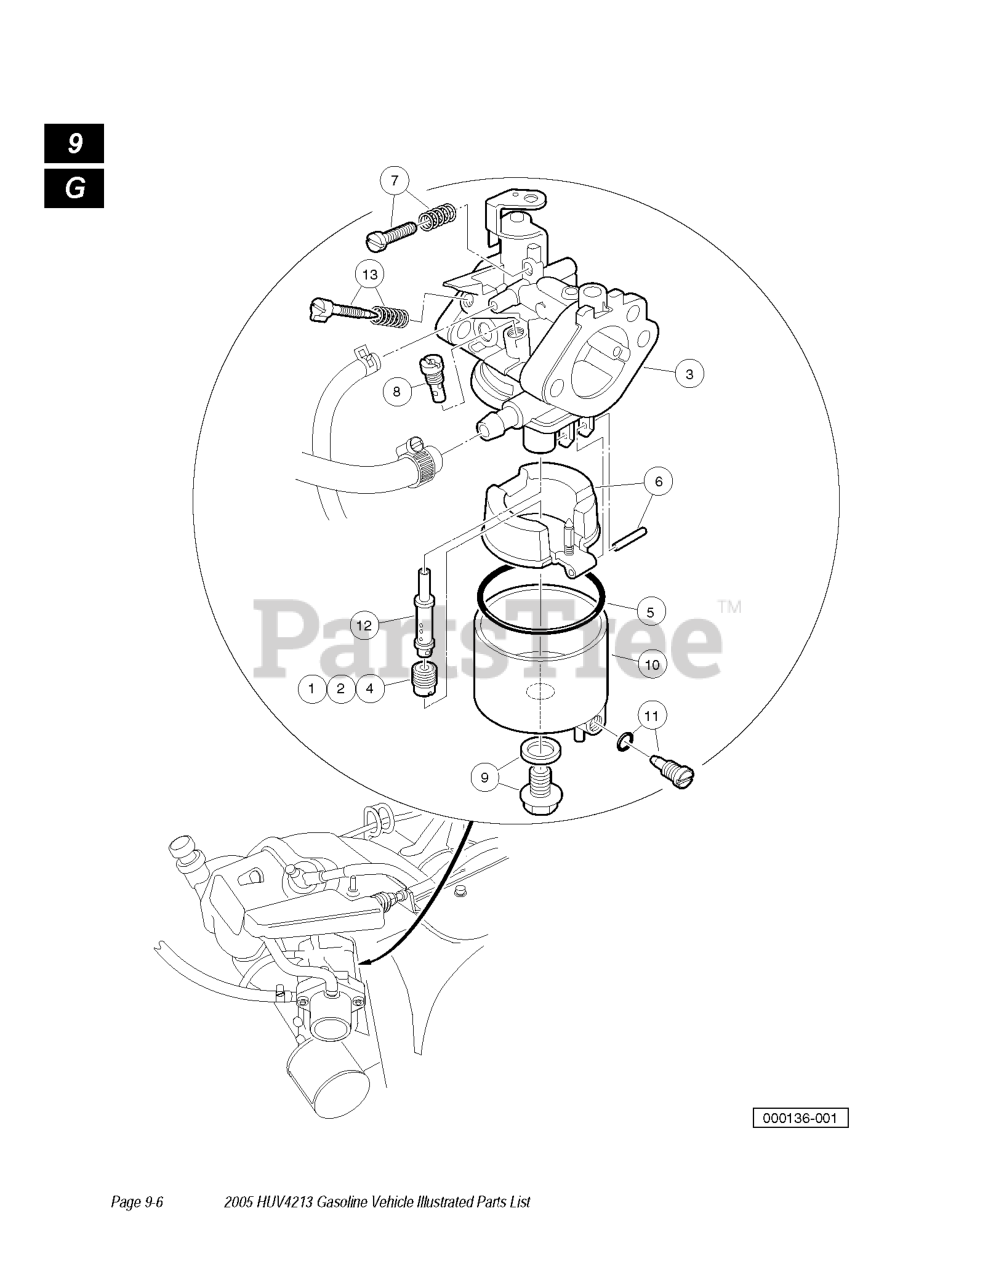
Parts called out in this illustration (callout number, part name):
1	JET, HIGH ALTITUDE OHV
2	HIGH ALTITUDE JET
3	FE400 CARBURETOR ASSY
4	HIGH ALTITUDE JET
5	GASKET, CARB. BOWL OHV
6	FLOAT ASSEMBLY
7	SCREW ASSEMBLY
8	JET, #45 PILOT
10	CHAMBER ASSEMBLY - FLOAT
11	SCREW ASSEMBLY
12	Nozzle, Main, Carburetor
